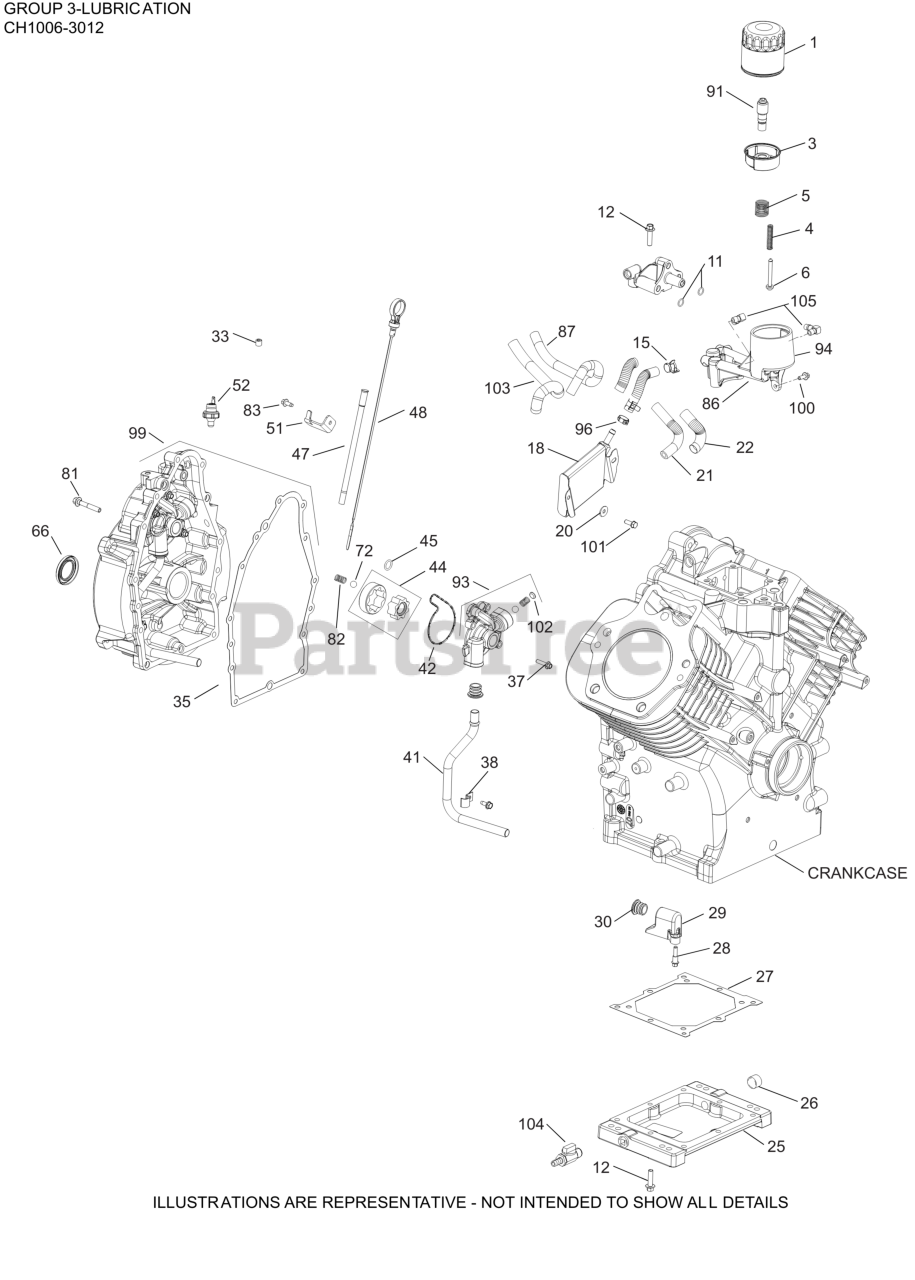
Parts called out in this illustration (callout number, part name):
1	OIL FILTER
3	CUP, OIL FILTER ASSEMBLY
4	SPRING, OIL FILTER VALVE
5	SPRING, OIL FILTER CUP
6	VALVE, OIL FILTER
11	O-RING, OIL PICK-UP
12	SCREW, FLG M8X1.25X30
15	SPRING CLAMP, HOSE
18	COOLER, OIL ASSEMBLY
20	WASHER, FLAT 1/4"
21	HOSE, OIL SUPPLY
22	SLEEVE, ANTI ABRASION-USE 25 431 12-S
25	OIL RESERVOIR
26	BUSHNG,REDCR 1/2"-1/8" NPT STL
27	GASKET, OIL RESERVOIR
28	SCREW, SHD THD FRM M6X.0X6.5
29	HOUSING, OIL PICK-UP ASSEMBLY
30	SEAL, PICK-UP TUBE
33	PLUG, CTSK PIPE 1/8"
35	GASKET, OIL PAN
37	SCREW, HEX FLANGE M6 X 1
41	TUBE, OIL PICK-UP
42	O-RING, OIL PUMP HOUSING
44	PUMP ASSEMBLY, OIL/GEROTOR
47	KIT, DIPSTICK TUBE
51	BRACKET, DIPSTICK TUBE
52	SWITCH, OIL PRESSURE
66	SEAL, OIL (LEFT-HAND HELIX, PTO)
72	PRESSURE RELIEF BALL
81	SCREW, HEX FLANGE
82	SPRING, COMPRESSION
83	SCREW, THREAD FORMING
86	HOUSING, HORIZ OIL FILTER-MACHINED
87	HOSE, OIL RETURN (MARINE)
91	NIPPLE, OIL FILTER ASSEMBLY
93	ASSEMBLY, OIL PUMP HOUSING
94	HOUSING, OIL FILTER ASSEMBLY
96	CLAMP, HOSE OETIKER
99	KIT, CLOSURE PLATE
100	SCREW,HEX FLNGE
101	SCREW, HEX HEAD
102	PLUG, CUP
103	SLEEVE, ANTI ABRASION
104	VALVE, OIL DRAIN
105	CONNECTOR, HOSE
